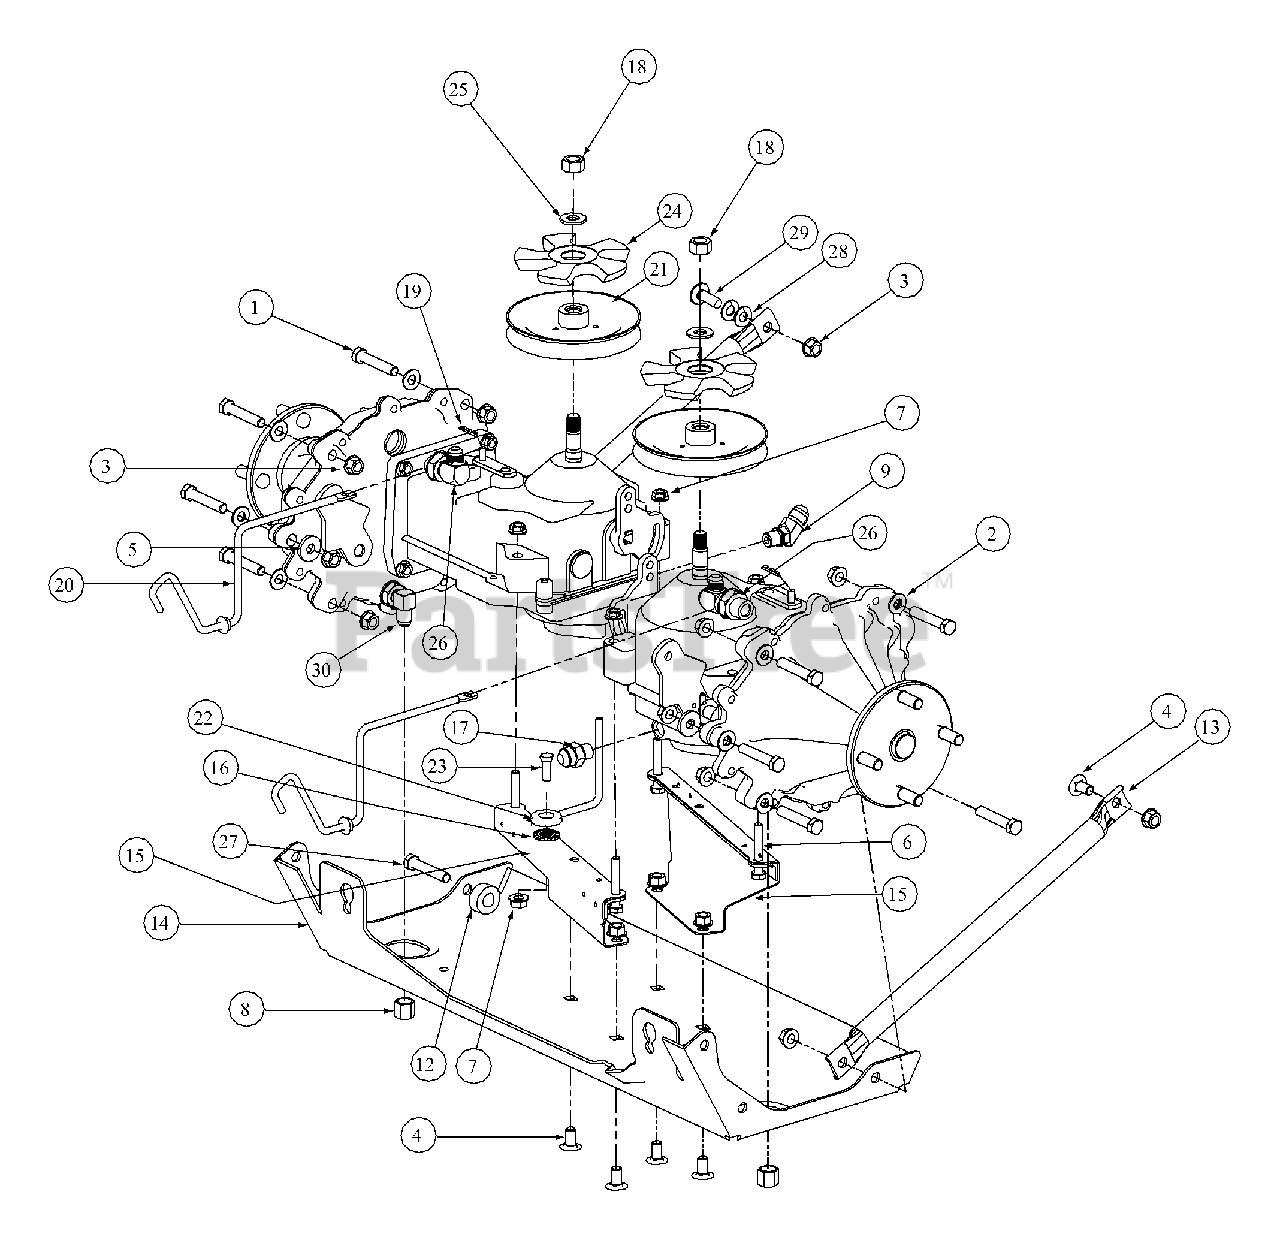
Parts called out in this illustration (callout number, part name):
1	HHCS, 3/8-16, 2.00
2	Flat Washer, 3/8, SAE
3	Hex Nut, 3/8-16, Flange Lock
4	Carriage Bolt, 3/8-16 x .75 Long
5	Flat Washer, .385 x 1.0 OD x .13
6	HHCS, 5/16-18, 2.00
7	Lock Nut, Hex Flange, 5/16-18
8	Nut, Cap, 3/8
9	Elbow Fitting, 3/8-1/2, 45 degree
12	Spacer, .406 ID x 1.00 OD x .38
13	Strut, Frame
14	Plate Assembly, Skid
15	Bracket Assembly, Support Pump
16	External Tooth Washer
17	Fitting Connector, 1/2 x 3/8
18	Nut, 1/2-20, Hex Insert Lock Jam
19	Hair Pin, .0721 x 1.12 Long
20	Rod, Release, Pump
21	Pulley, Transmission Hydro, Slotted
22	Guide, Traction Drive Belt
23	Flat Head Screw, 5/16-18 x 1.00
24	Hydro Pulley Fan
25	1/2" Flat Washer
26	Fitting Elbow, 3/8 x 3/8
27	Hex Cap Screw, 3/8-16, 2.50
28	Lock Washer, 3/8
29	Carriage Bolt, 3/8-16 x 1
30	Fitting Elbow, 3/8 x 3/8
